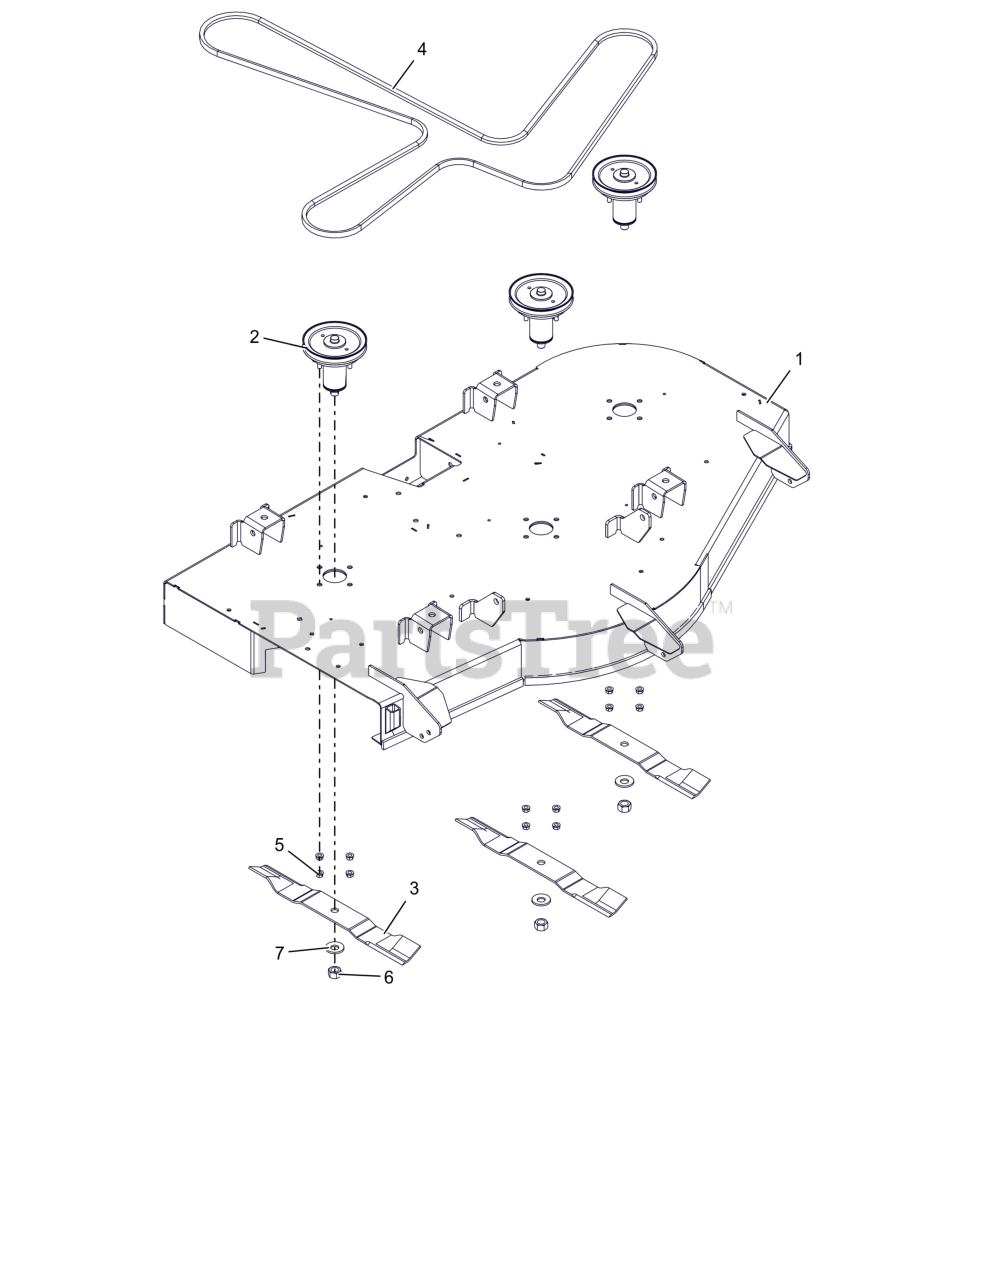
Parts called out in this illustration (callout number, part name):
1	KIT, 52" ARIENS DECK W/DECALS
2	KIT- DECK SPINDLE ASSM- 52"
3	BLADE, 18" - 30 DEG .5 OFFSET
4	V-BELT, HA-WRAPPED
5	NUT,LK-CTR-FLG .31-18 GF ZCC
6	NUT-STD .625-18 ZCC
7	WSHR-BLVL .669X1.535X.138
